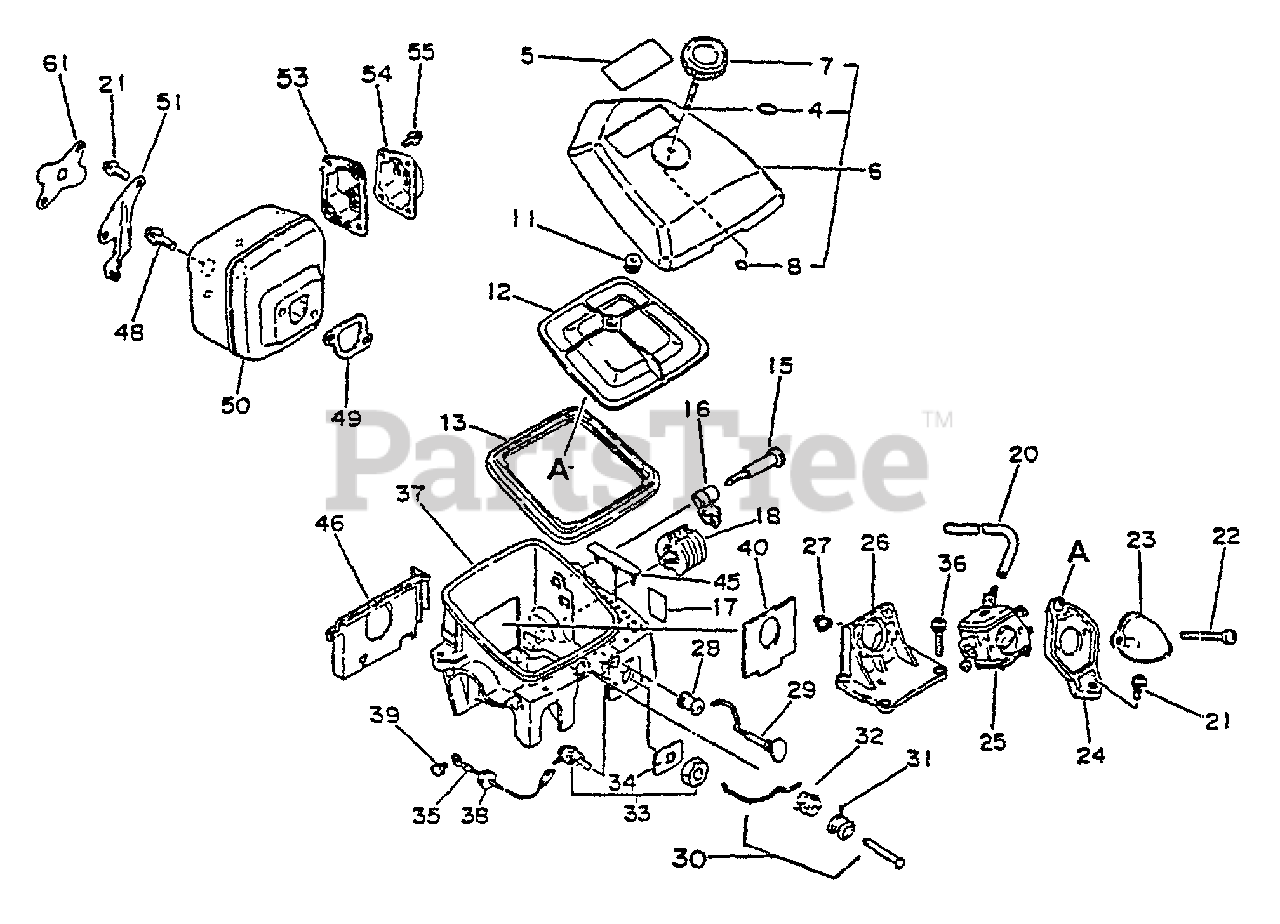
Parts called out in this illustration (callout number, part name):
4	O-RING - 10
5	LABEL - MODEL
6	AIR FILTER COVER ASSY
7	THUMBSCREW
8	O-RING - 3
12	FILTER, AIR
13	SEAL
15	SCREW, IDLE ADJUST
20	PIPE - IMPULSE
21	SCREW - 5X14
22	SCREW - 5X55
23	ELBOW, INTAKE
24	BRACKET, AIR CLEANER
25	CARBURETOR HDA-45
26	INSULATOR, INTAKE
27	NUT
29	ROD, CHOKE
30	ROD, THROTTLE
32	GUIDE, THROTTLE ROD
33	IGNITION SWITCH ASSY
34	LABEL - STOP
35	LEAD - GROUND
36	SCREW - 5X25
37	CASE, CARBURETOR
39	SCREW - 4X8
40	SEAL, DUST
46	PLATE, GUIDE
48	SCREW - 6X20
49	GASKET, EXHAUST
51	BRACKET, MUFFLER
53	SCREEN, SPARK ARRESTOR
54	LID, MUFFLER
55	SCREW - 4X10
61	COVER, MUFFLER
65	AIR CLEANER ASSY
66	BRACKET, AIR CLEANER
67	GASKET
